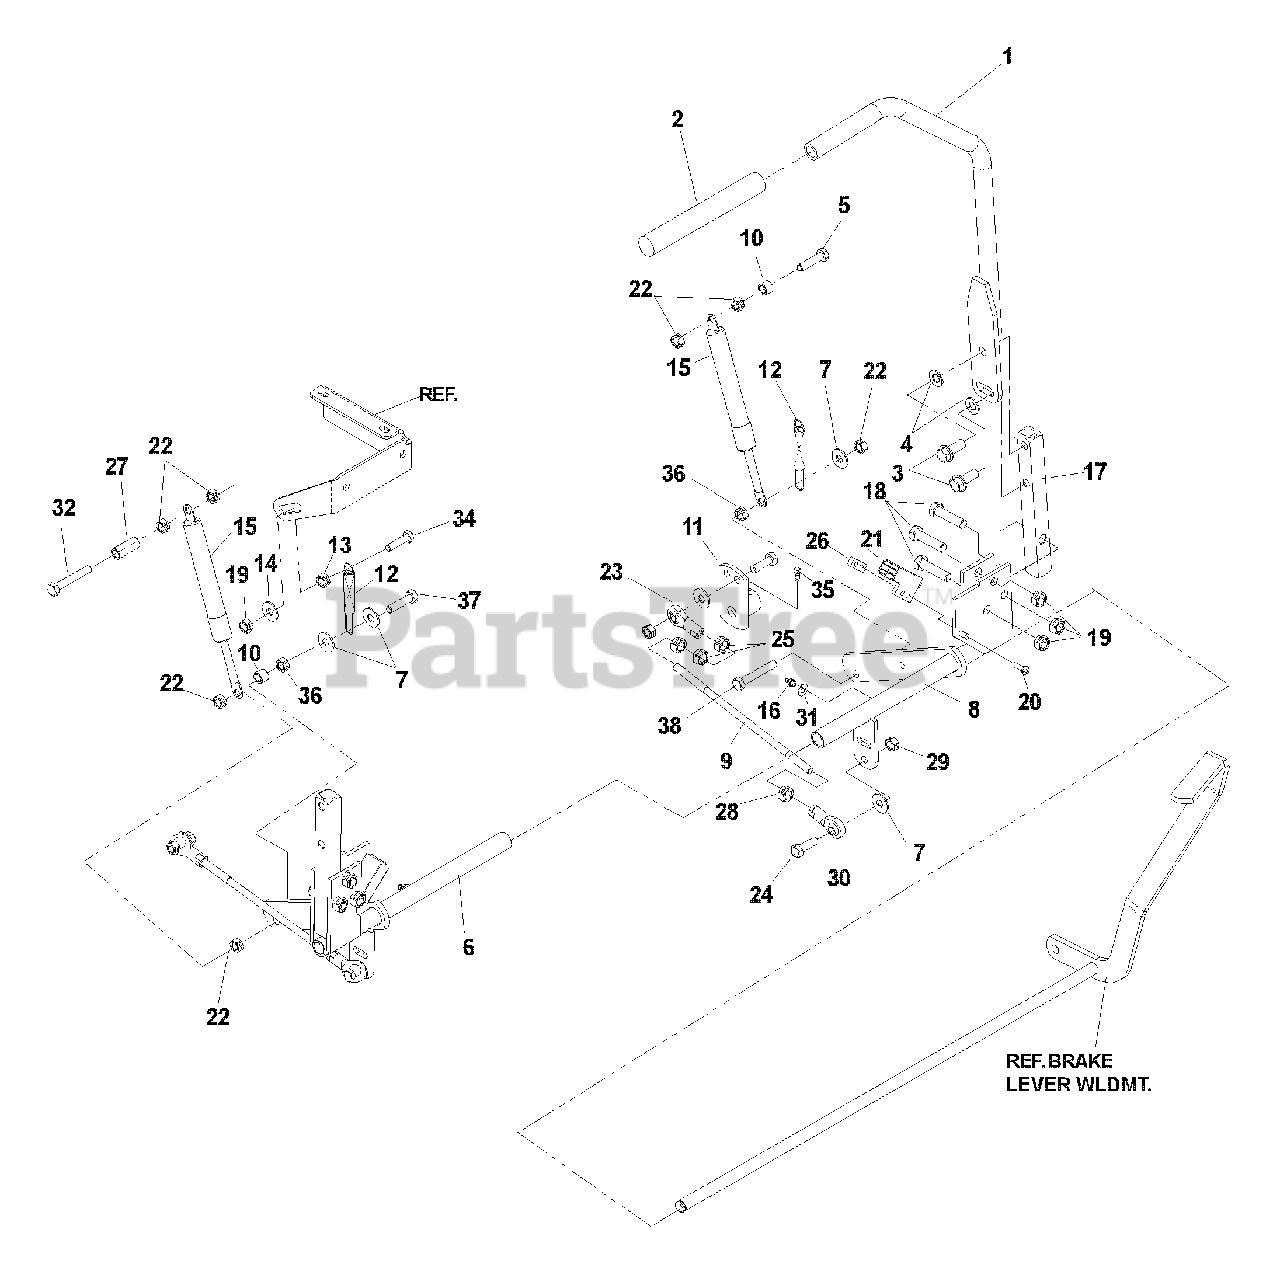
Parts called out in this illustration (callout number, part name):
1	CONTROL LEVER WLDMT
3	HCS 3/8C X 1
4	3/8 DISC SPRING WASHER
5	HCS 5/16C X 1 1/2
6	CONTROL WELDMENT, RIGHT
7	WASHER 5/16 FLAT
8	CONTROL WELDMENT, LEFT
9	PUMP CONTROL LINK
11	CONTROL ARM, PUMP
13	3/8C WHIZ NUT
14	WASHER 3/8 FLAT
16	ZERK
17	CONTROL ARM
18	HCS 3/8C X 1 3/4
19	NUT, 3/8C, NYLOC
20	SCREW 310-24 X 5/8
22	NUT, 5/16C, CENTERLOCK
23	BALL JOINT, RIGHT
24	HCS 5/16C X 1 1/4
25	NUT, 5/16-24
26	TAPPED PLATE
28	NUT, 5/16F, LEFT HAND
29	NUT, 5/16C, NYLOC
30	BALL JOINT, LEFT
32	HCS 5/16C X 2
34	HCS 3/8C X 2 1/2
35	SCREW, 5/16C X 5/8, SET
36	NUT 5/16C, WHIZ
37	BOLT, 5/16C X 2 1/4, TAP
38	BOLT, 5/16C X 1 1/4, TAP
